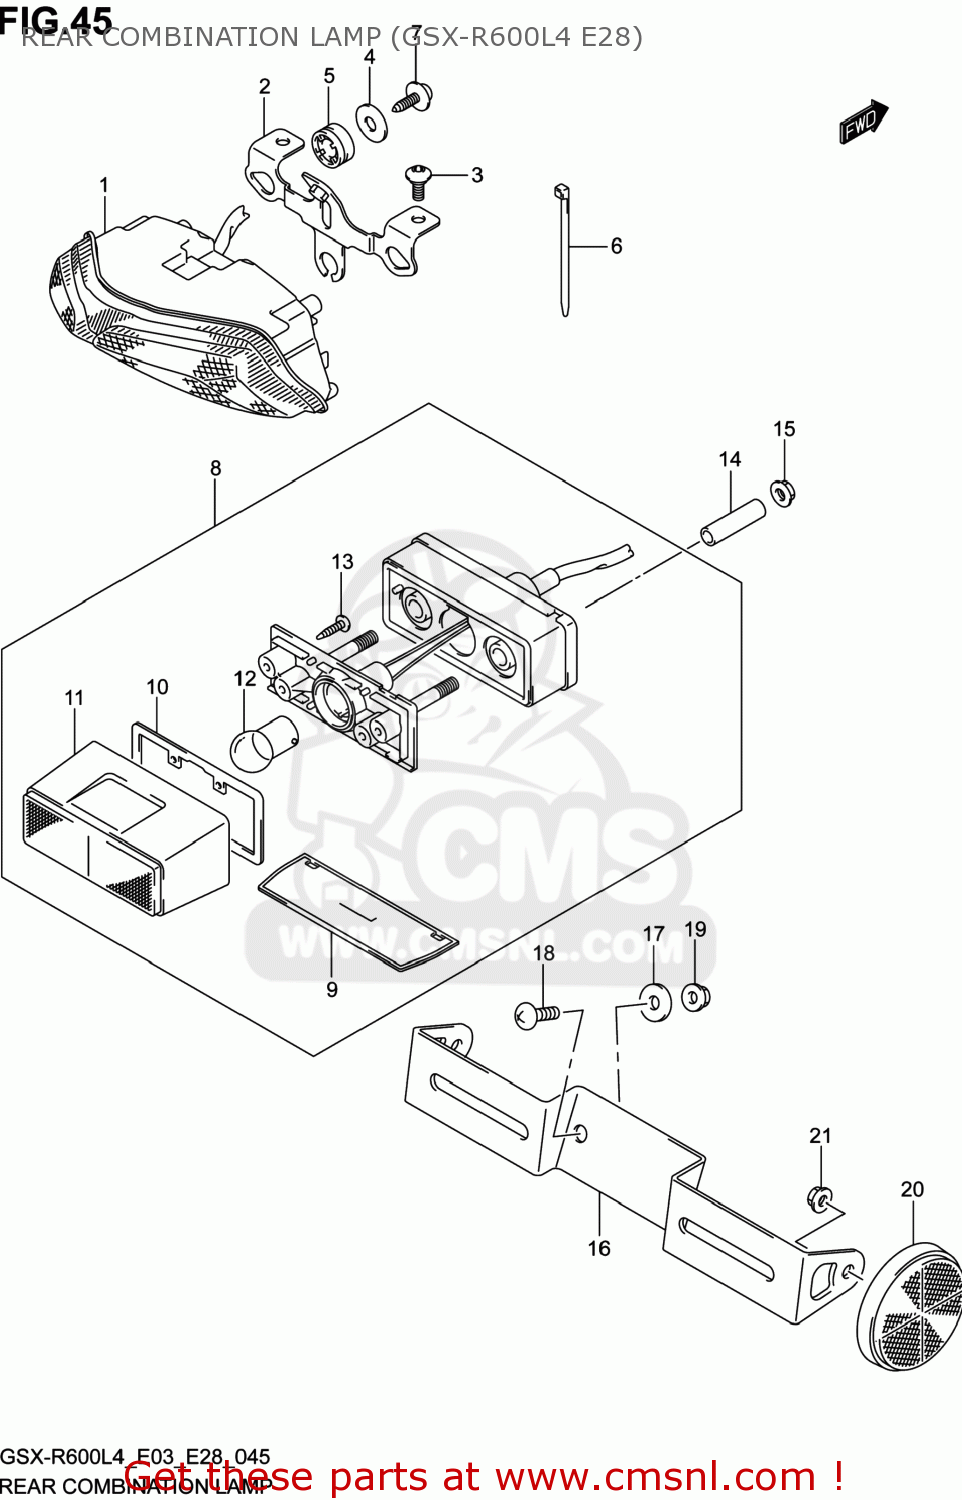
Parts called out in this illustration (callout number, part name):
1	LAMP ASSY,RR COMBINATION
2	BRACKET,RR COMBINATION LAMP
3	BOLT(5X13)
4	WASHER(5.5X20X1.2)
5	CUSHION
6	CLAMP(L:100)
7	SCREW
8	LAMP ASSY,LICENSE
9	LENS,LICENSE LAMP
10	GASKET (NAS)
11	COVER,LICENSE LAMP
12	BULB(12V5W,BF150-40160A)
13	SCREW
14	SPACER(6.5X9X34)
15	NUT
16	BRACKET,LICENSE PLATE
17	WASHER(6.5X20X1.2)
18	SCREW
19	NUT
20	REFLECTOR ASSY,RR SIDE
21	NUT
